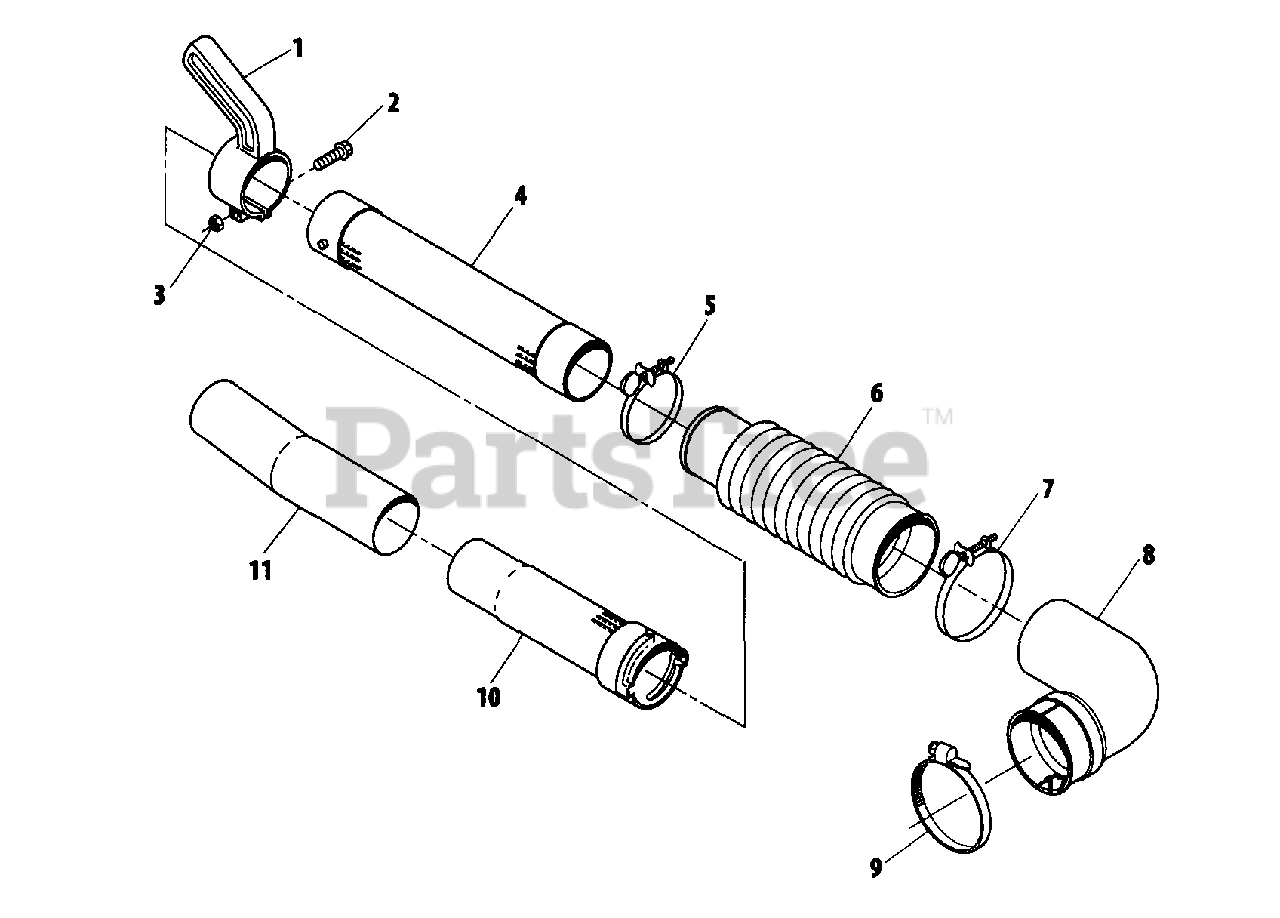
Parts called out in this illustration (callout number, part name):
1	HANDLE
2	BOLT
3	NUT, HEX M6
4	TUBE, BLOWER - SWIVEL
5	CLAMP
6	TUBE, BLOWER - FLEXIBLE
7	CLAMP
8	TUBE, BLOWER - ELBOW
9	CLAMP
10	TUBE, BLOWER - EXTENSION
11	TUBE, BLOWER - ROUND NOZZLE
